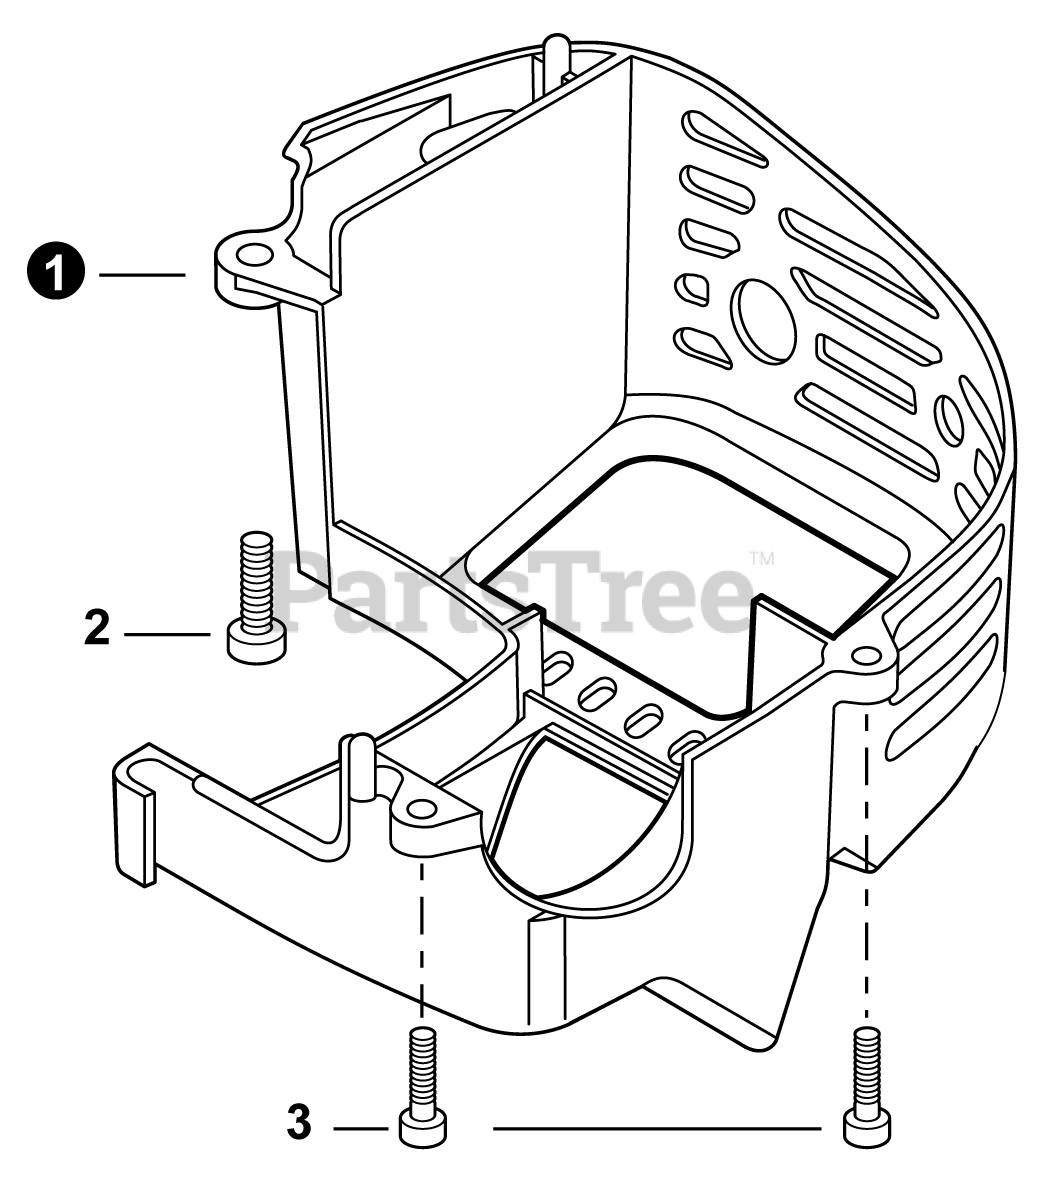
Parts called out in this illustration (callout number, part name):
1	COVER, ENGINE
2	BOLT, TORX 5×16
3	BOLT, TORX 4×16
